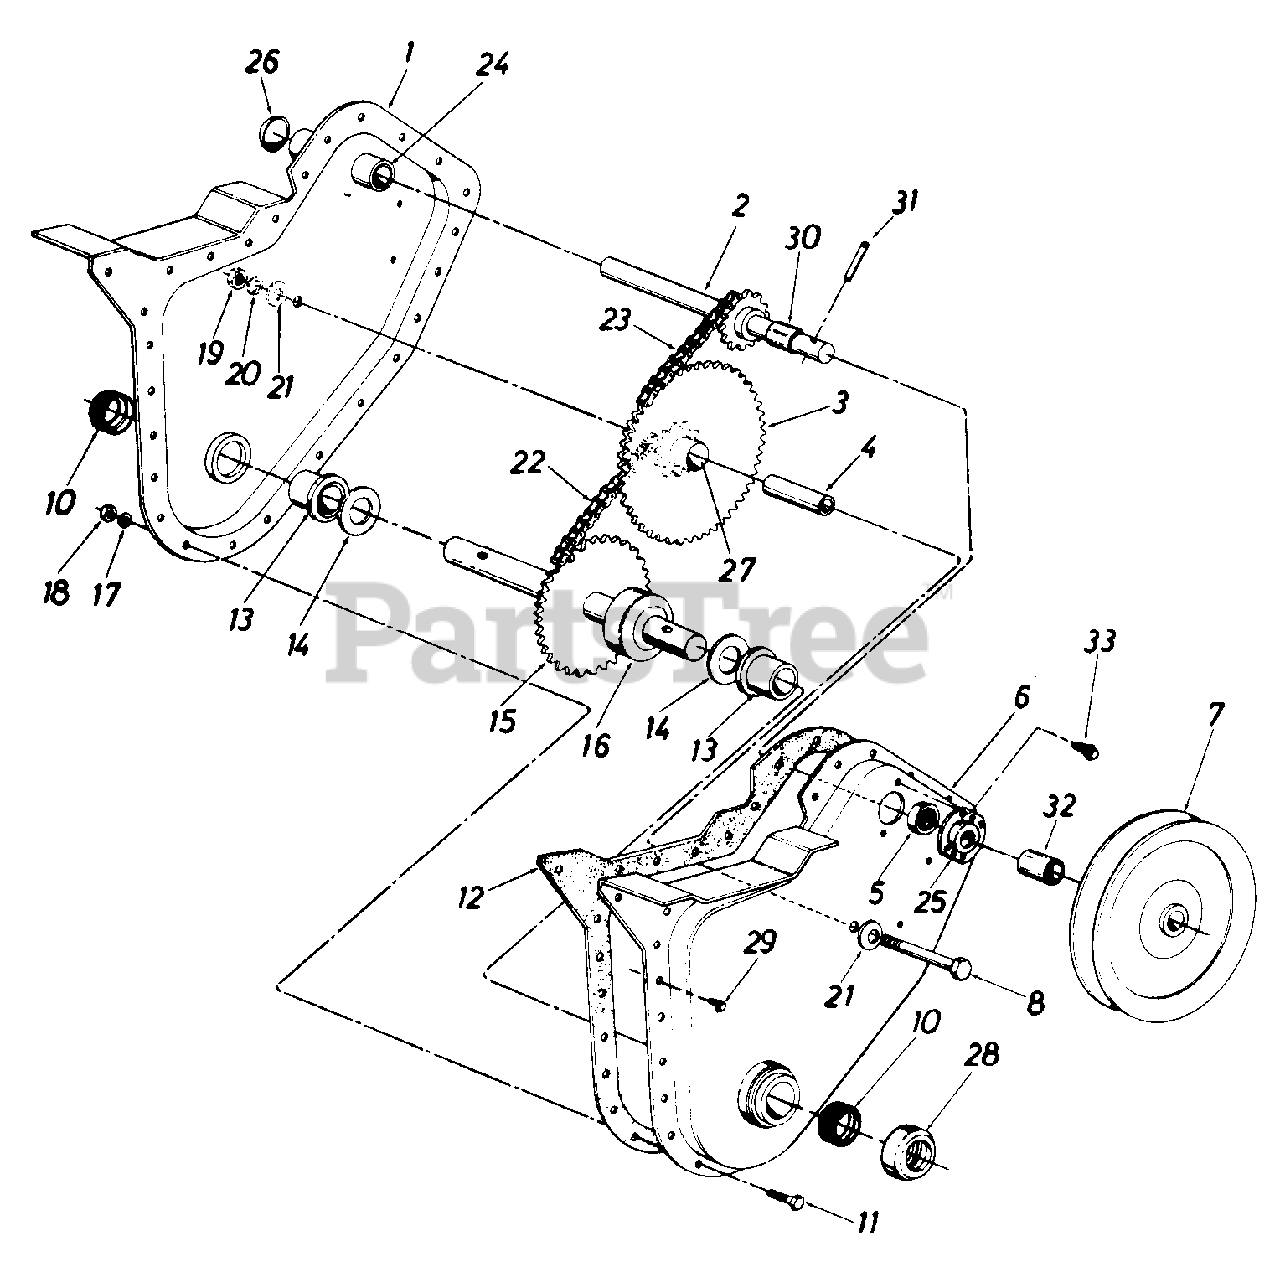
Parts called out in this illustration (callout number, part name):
1	HOUSING-CHAIN-CASE RH
2	SHAFT ASSY-INPUT
3	SPROCKET & HUB ASSY
4	BEARING-INNER RACE
5	BEARING-BALL
6	CHAIN CASE HSG-LH
8	SCREW-HEX 3/8-24 X 2.50
11	SCREW-HEX 1/4-28 X .62
12	GASKET
13	BEARING-FLANGE
14	WASHER-FL-.88 X 1.50 X .030
15	SHAFT ASSY-TINE
16	SPACER
17	LOCK WASHER 1/4 DIA
18	NUT-HEX 1/4-28
19	NUT-HEX INS L-3/8-24
20	WASHER-LOCK-3/8
21	WASHER-BELL .3/8ID X 1.12OD X .030
22	#420 CHAIN 1/2 PITCH X 38 LINKS
23	#35 CHAIN 3/8 PITCH X 50 LINKS
25	HOUSING-BRG
26	PLUG-EXPANSION
27	BEARING-SLEEVE
29	SCREW-HEX WASH SF TAPP
31	PIN-SPRING SPIRAL 1/4X1.5 HEAVY DT
33	SCREW-TAP 1/4-20 X .38
